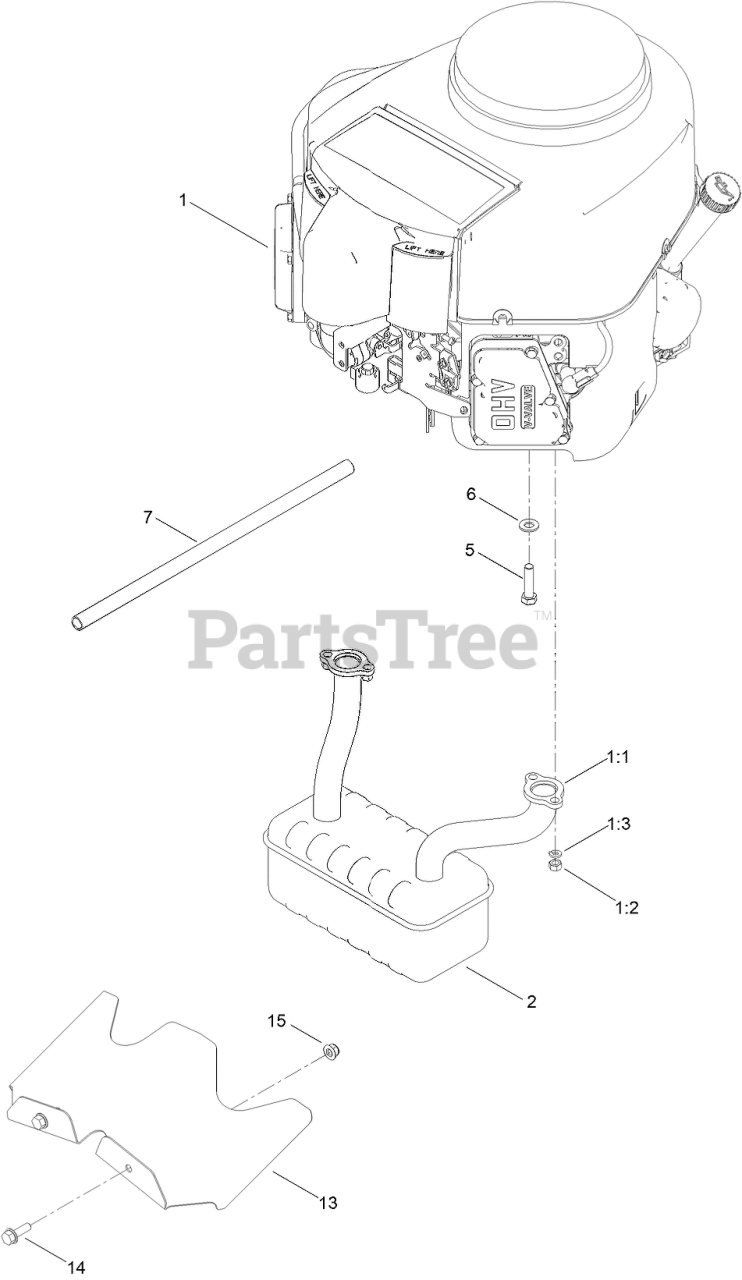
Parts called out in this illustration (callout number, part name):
1:1	GASKET-EXHAUST
1:3	WASHER-LOCK
2	MUFFLER
5	BOLT-HH
6	WASHER-FLAT
7	TUBE-DRAIN, OIL
13	SHIELD-HEAT
14	SCREW-HHF
15	NUT-HF, NI
